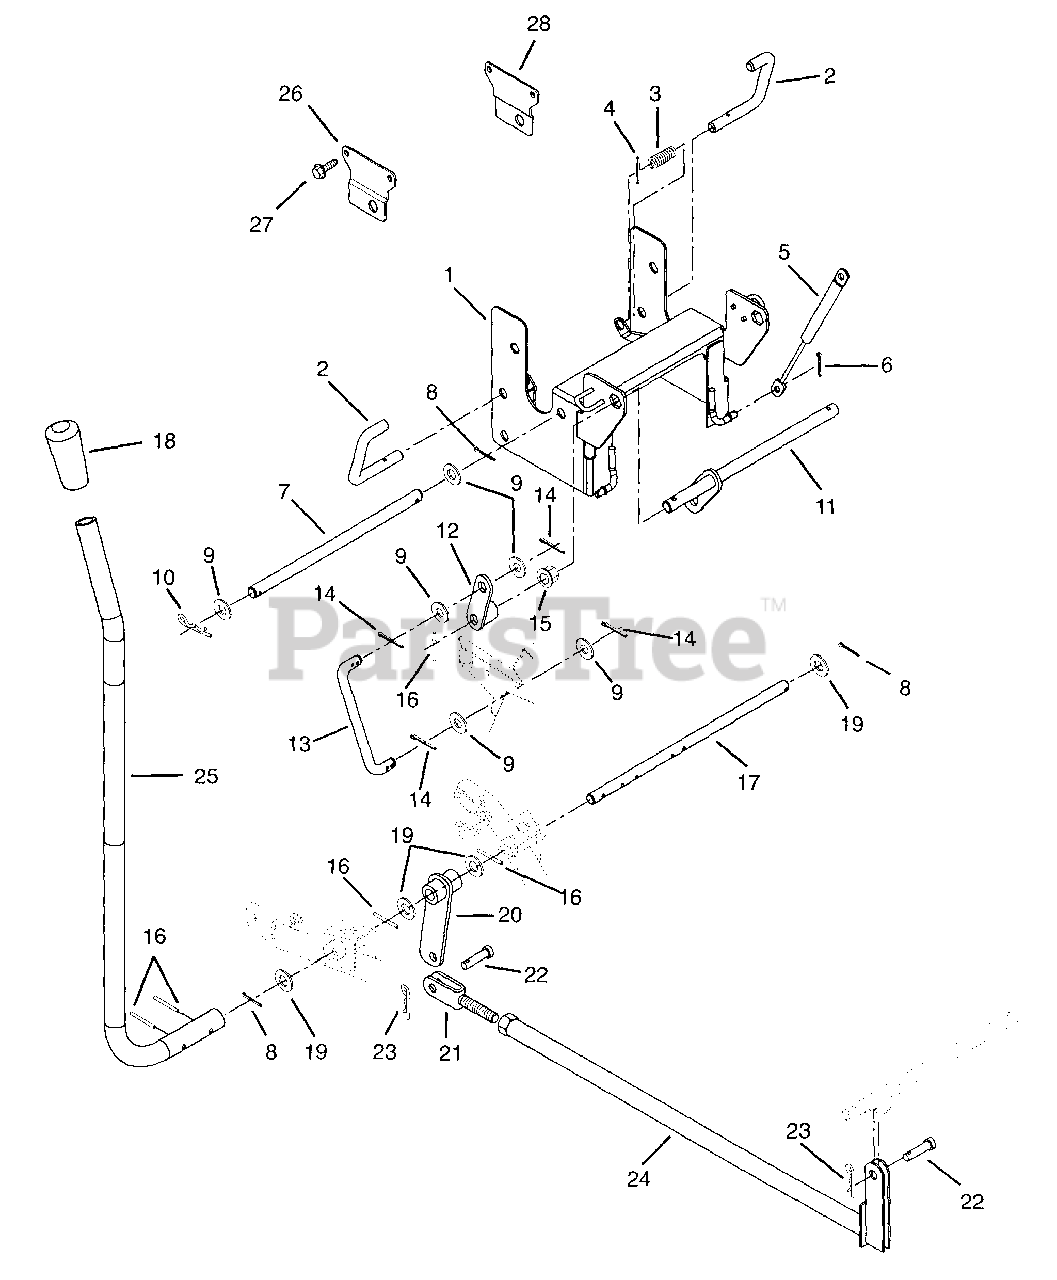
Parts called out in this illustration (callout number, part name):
1	FRAME, PIVOT
2	PIN, LATCH
3	SG-COMP .072X.77X1.75
4	PIN-ROLL .188X1.00
5	SG-GAS COMP .315X.75X10.00 120
6	@PIN-CTR .12X.75 EXTPRSQCT YWZ
7	ROD, PIVOT
8	@PIN-CTR .12X1.25 EXTPRSQCT YZ
9	@WSHR-FL-STL.656X1.31X.095 YWZ
10	PIN-HAIR-INT .17X.68X3.50 YWZC
11	PIVOT ROD
12	ARM, LIFT
13	LINK, LIFT
14	@PIN-CTR .12X1.00 EXTPRSQCT YZ
15	BSHG-FLG .750X.873HEXX.53X1.18
16	PIN-GRV .250X1.50 TP A
17	PIVOT ROD
18	GRIP,HANDLE BAR
19	WSHR-FL-STL.754X1.125X.062YWZC
20	LEVER, ACTUATOR
21	CLEVIS R.H.
22	PIN-CLEV .494X1.25 YWZC
23	PIN-HAIR INT .14X.4X2.75
24	TUBE, LIFT
25	LEVER
26	MOUNT - PIVOT FRAME RH
27	@SCR-TAP .38-16X.50 HWH TR YWZ
28	MOUNT - PIVOT FRAME LH
